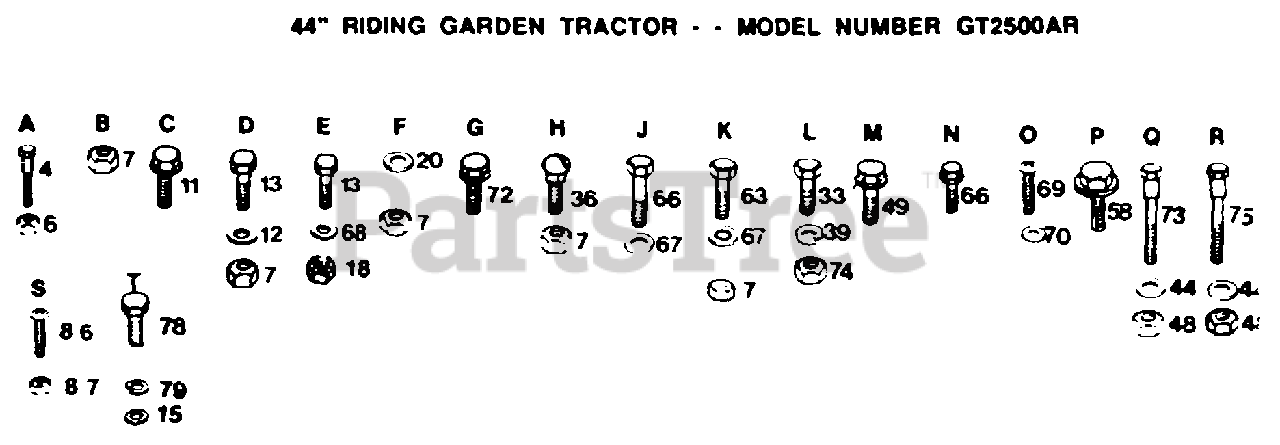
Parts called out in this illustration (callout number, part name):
11	SCREW
12	WASHER
15	WASHER
18	NUT
20	WASHER
33	BOLT LT
36	BOLT
39	LOCKWASHER
49	SCREW LT
63	BOLT
66	SCREW GTV
67	WASHER HYT
68	WASHER
69	SCREW
73	BOLT T
75	SHOULDER BOLT ST
78	BOLT
79	LOCKWASHER
87	"NUT,KEPS"
